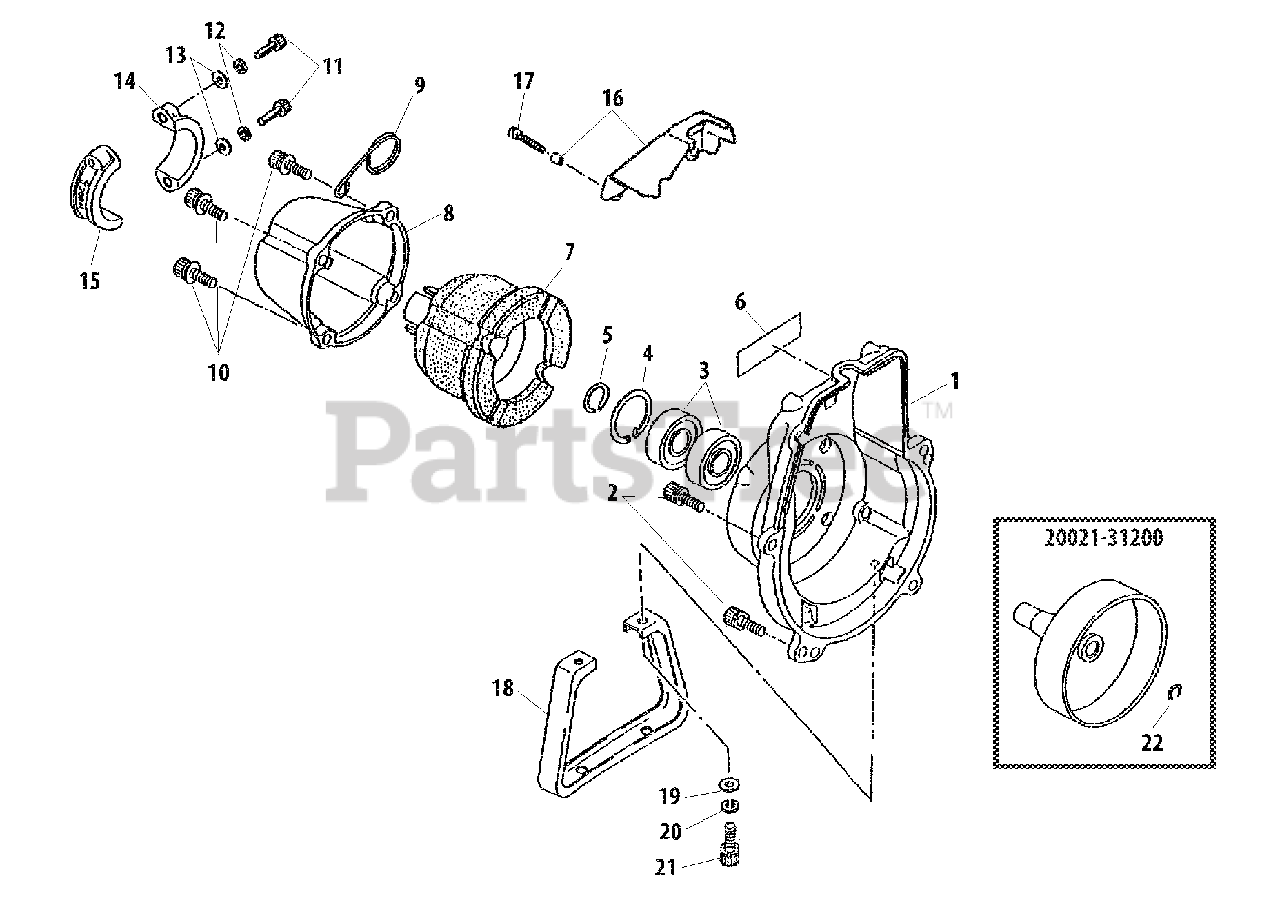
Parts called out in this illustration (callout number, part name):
1	CASE, FAN
2	SCREW - 5X20
3	BEARING, BALL - 6002
4	RING, RETAINING - 32
5	RING, RETAINING
6	LABEL - MODEL
7	CUSHION
8	CONNECTOR, CAP
9	HOLDER, CABLE
10	SCREW - 5X20
11	SCREW - 5X25
12	LOCKWASHER - 5
13	WASHER - 5
14	CLAMP - B
15	CLAMP - A
16	PROTECTOR
17	SCREW - 4X16
18	STAND
19	WASHER - 5
20	LOCKWASHER - 5
21	BOLT
22	RING, RETAINING - 11
20021-31200	CLUTCH DRUM KIT
